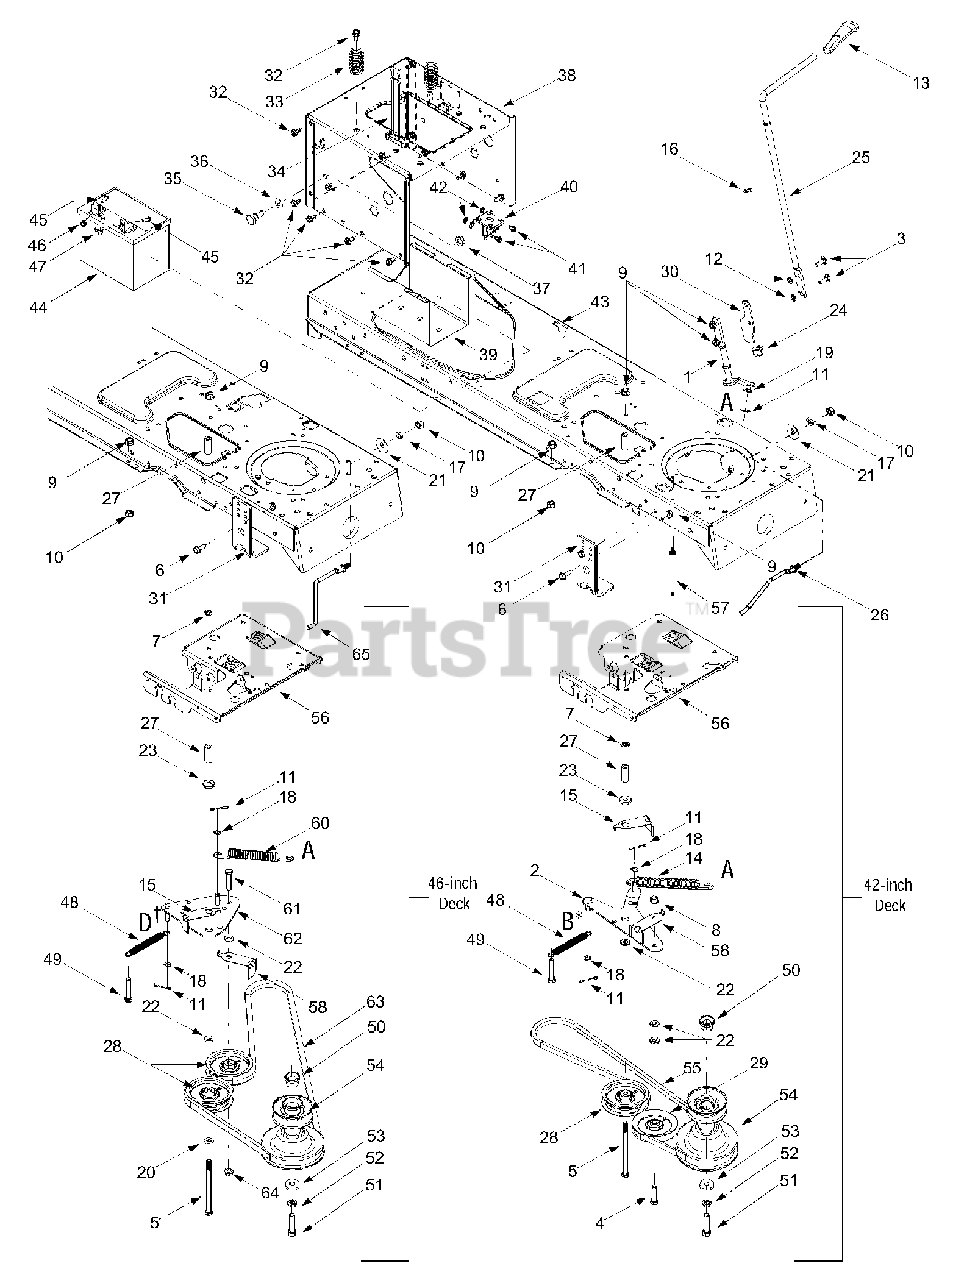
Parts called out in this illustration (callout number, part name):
1	PTO Engage Lever Assembly
4	Hex Cap Screw, 3/8-16 x 1.5
5	Hex Cap Screw, 3/8-16 x 5.5
6	Hex Head Washer Screw, 5/16-18 x .875
7	Push Nut, 3/8
8	Flange Lock Nut, 3/8-16
9	Flange Lock Nut, 5/16-18
10	Hex Nut, 5/16-18
11	Cotter Pin, 1/8 x 1.25
12	Speed Nut, .3125
13	PTO Knob
14	Extension Spring, .75 x 6.75
15	Belt Guard
16	Flat Washer, .510 x .750 x .033
17	Lock Washer, 5/16
18	Flat Washer, .385 x .62 x .063
19	Flat Washer, 5/16
20	Flat Washer, .406 x .875 x .059
21	Bell Washer, .39 x 1.13 x .062
22	Flat Washer, .407 x .812 x .135
23	Shoulder Spacer, .380
24	Hex Split Flange Bearing, .5
26	Belt Keeper Rod
27	Spacer, 3/8 x 1.54
28	Idler Pulley, 3.5
29	Idler Pulley, 4.0
32	Self Tapping Screw, 5/16-18 x .625
33	Compression Spring, 1.28 x 3.5
34	Battery Strap
35	Shoulder Screw, .625 x .5, 7/16-20
36	Bell Washer, .45 x 1.0 x .062
37	Flange Lock Nut, 7/16-20
41	Self Tapping Screw, 1/4-20 x .5
42	Lock Washer, 1/4
45	Hex Cap Screw, 1/4-20 x .62
46	Hex Sems Nut, 1/4-20
47	Wing Nut, 1/4-20
48	Extension Spring, .50 x 5.0
49	Hex Cap Screw, 5/16-18 x 1.75
50	Spacer Cup
51	Hex Head Cap Screw, 7/16-20 x 1.25
52	Lock Washer, 7/16
53	Flat Washer, .450 x 1.25
54	Engine Pulley, 3.56 OD x 5.56
55	PTO Belt
57	Keeper Pin, 5/16 x 4.75
58	Belt Guard
59	Hex Cap Screw, 5/16-18 x .625
60	Extension Spring, .75 x 6.75
61	Hex Cap Screw, 3/8-16 x 1.75
63	PTO Belt
64	Flange Lock Nut, 3/8-16
65	Belt Keeper Rod
